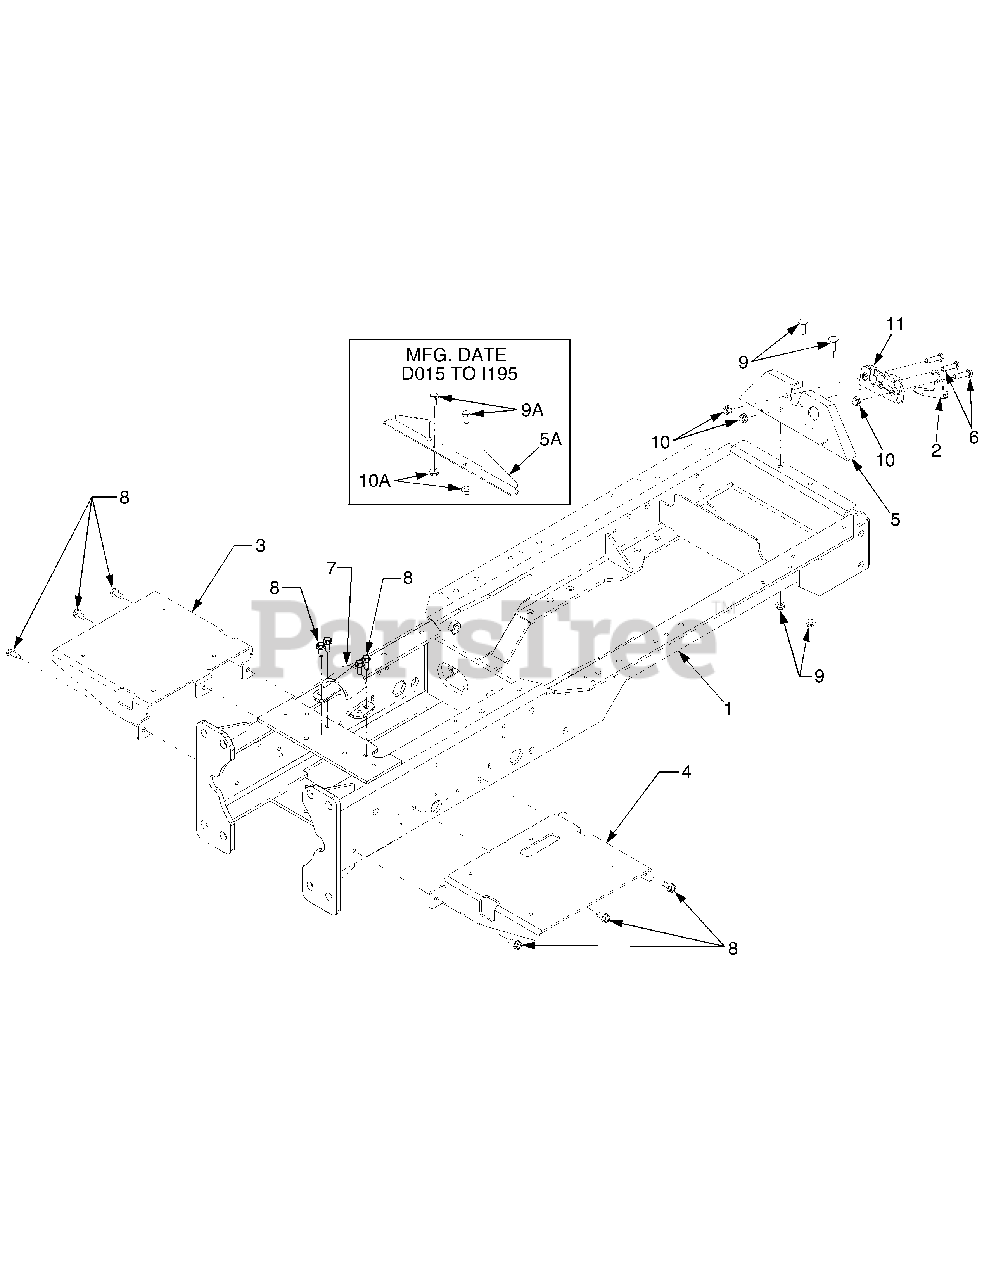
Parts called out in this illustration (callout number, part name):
1	Frame Assembly
2	Lever, Hood Latch - Original Style
3	Bracket, Runng Brd Mtg. LH
4	Bracket, Runng Brd Mtg. RH
5	Bracket, Hood Latch Mtg
6	Screw, Hex Cap, 5/16-18 x 1.375 GR5
9	Screw, Carriage, 5/16-18 x .75
9A	Screw, Hex Cap, 5/16-18 x .625 GR5
10	Nut, Hx Flange Lck, 5/16-18
10A	Nut, Hx Flnge Insert Lk, 5/16-
11	Latch, Hood
